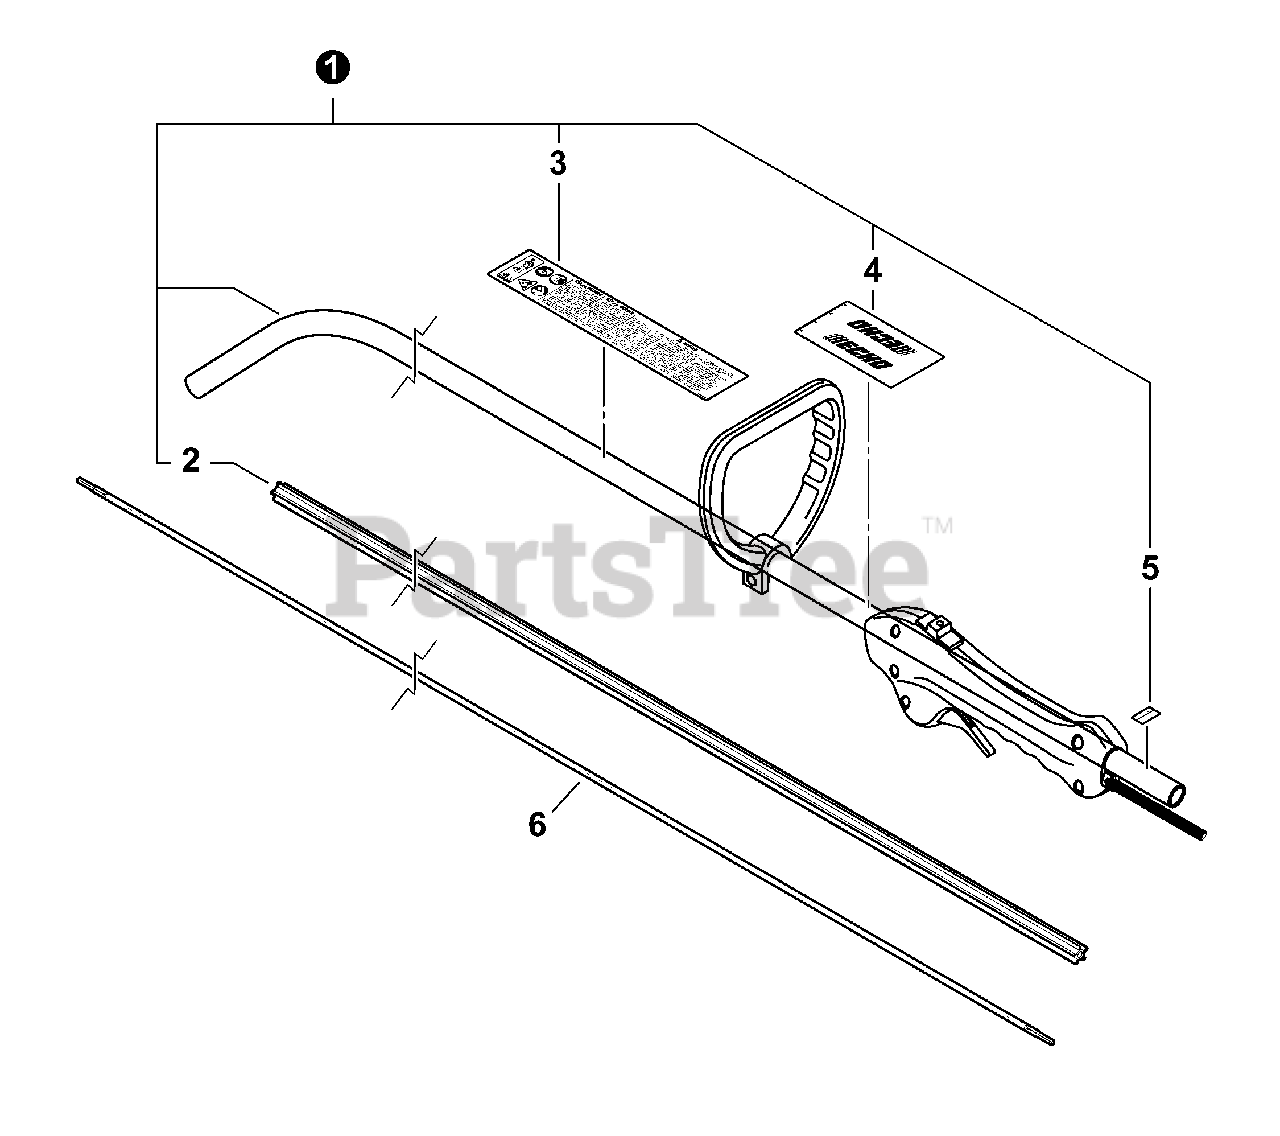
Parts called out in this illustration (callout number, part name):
1	MAIN PIPE ASSY
2	LINER - FLEXIBLE
3	LABEL, CAUTION
4	LABEL, HANDLE LOCATION
5	LABEL - ALIGNMENT
6	DRIVESHAFT - FLEXIBLE
